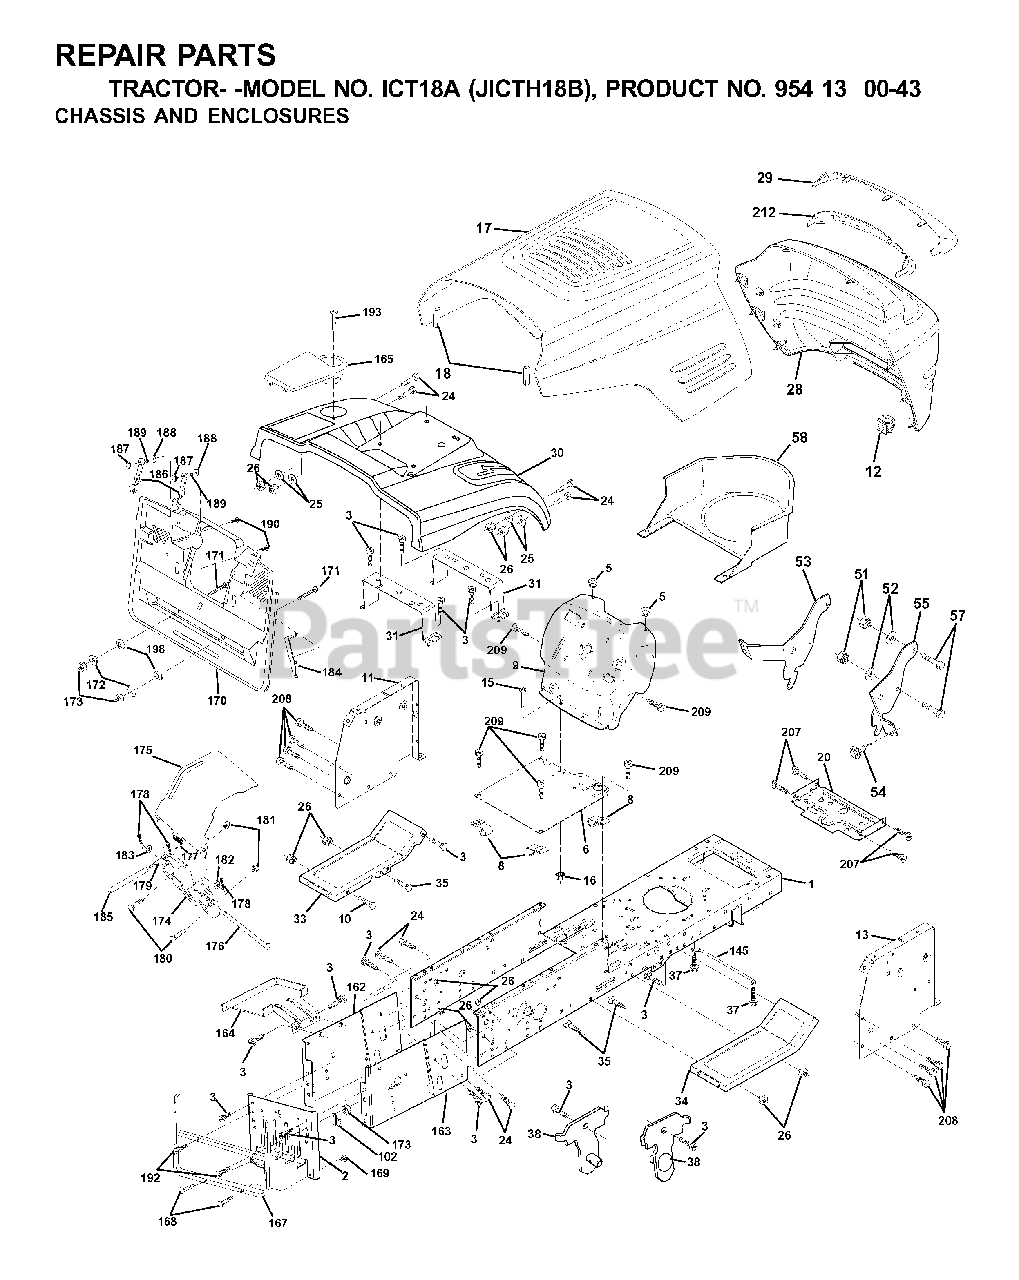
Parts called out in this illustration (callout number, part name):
1	CHASSIS STAMPING
3	SCREW 3/8-16X3/4
5	BUMPER.RUBBER.HOOD
6	SADDLE FLAT
8	CLIP,INSULATOR
10	BOLT D
11	PANEL DASH LH
13	DASH PANEL RH
16	NUT
18	BUMPER HOOD T
20	PLATE MTG
25	WASHER
26	NUT
31	BRACKET SUPPORT FENDER
38	BRACKET
51	LOCKNUT
57	BOLT
58	DUCT, INTAKE AIR
102	CLIP T
145	ROD PIVOT CHASSIS/HOOD
164	SUPPORT
168	BOLT.ROUND.HEAD.SQUARE.NECK
169	NUT T
170	BACKPLATE ASM
172	WASHER
176	HINGE PIN
177	SPRING COVER LH
178	COTTER PIN
179	ROD PIVOT
180	BOLT RB
181	LOCKNUT
185	TUBE LEVER
186	LATCH ASSY
187	WELDNUT
189	LOCKWASHER
193	SCREW, TRUSS 1/4-20 X 3/4"
207	SCREW, 5/16-18 X 1/2
208	SCREW 3/8-16X1/2
209	SCREW, 3/8-16X3/4
